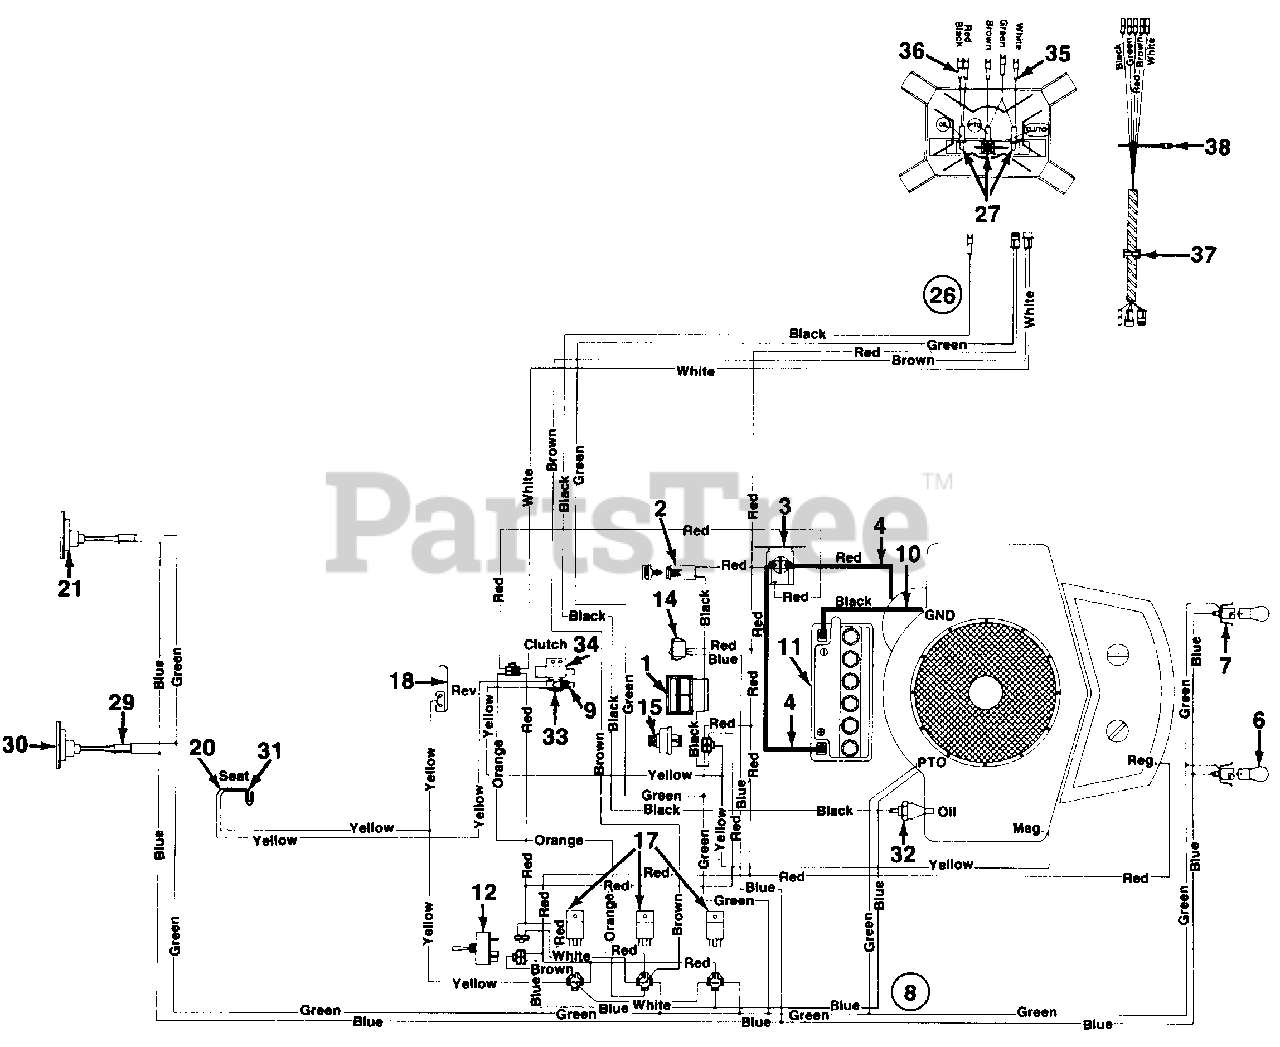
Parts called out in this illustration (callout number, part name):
1	Ammeter
2	Fuse 20 Amps
3	Solenoid
4	Wire
6	Bulb
7	Socket
8	Wire Harness
9	Safety Switch (Clutch)
10	6 Ga. Black Wire
11	Battery (275 Cold Crank Amps)
12	Switch (PTO)
14	Light Switch
15	Ignition Switch
17	Relay
18	Spring Lever
20	Safety Switch (Seat)
21	Taillight
26	Wire Harness
27	Bulb
29	Taillight Harness
31	Safety Switch (Seat)
32	Oil Pressure Switch
33	Safety Switch (Clutch)
34	Clutch Switch Mtg. Brkt.
35	Monitor Light Harness Dual
36	Monitor Light Harness Single
37	Wire Clip
38	Cable Tie
